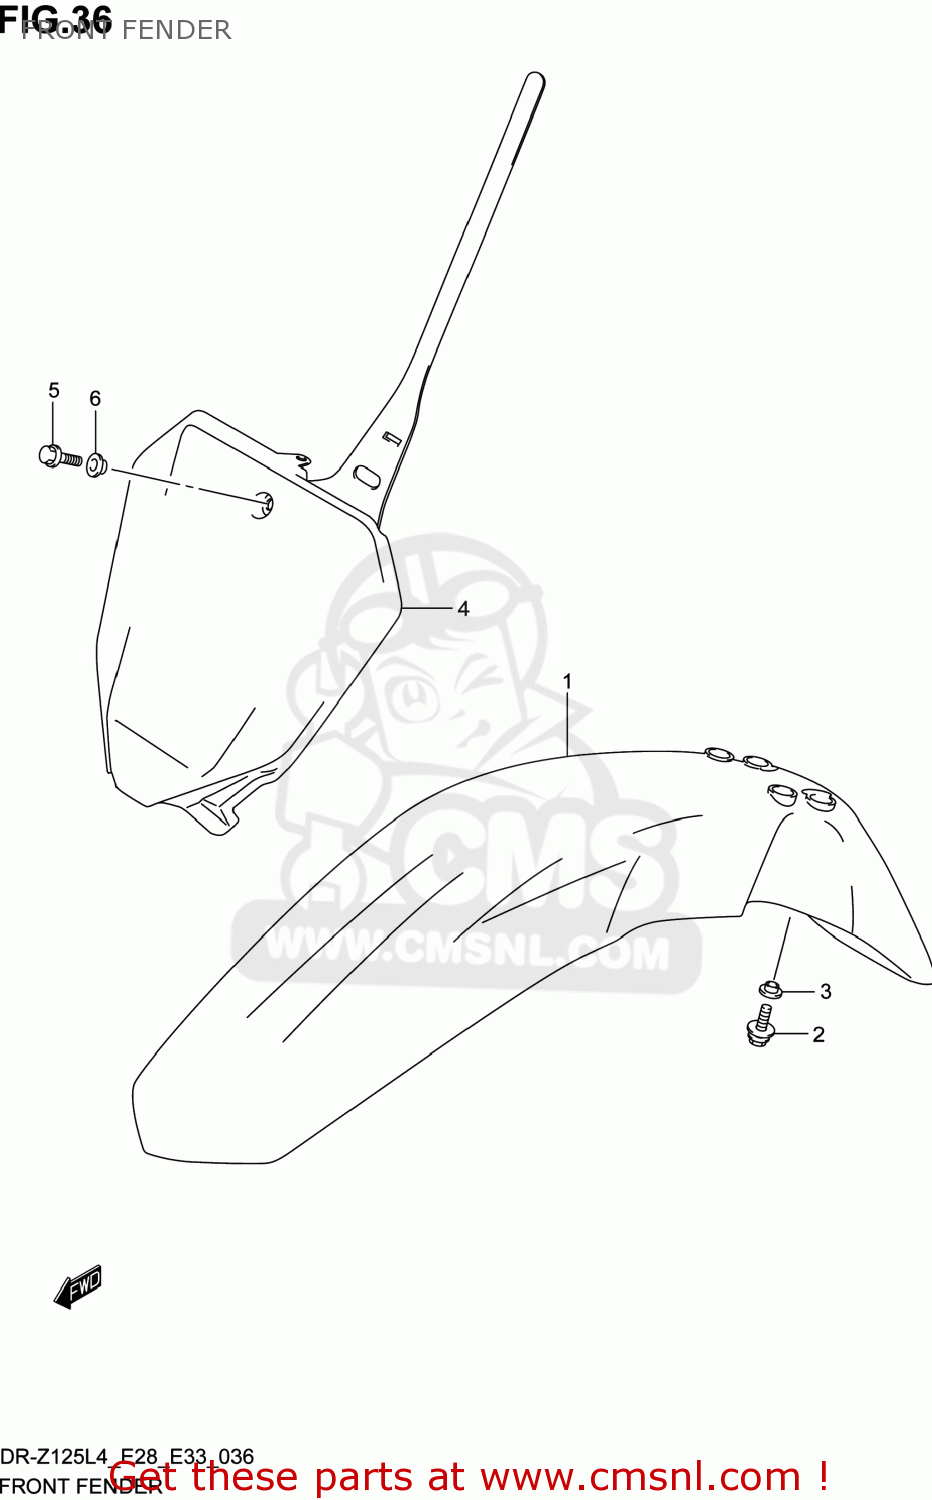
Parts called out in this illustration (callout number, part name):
1	FENDER,FR
2	BOLT(6X16)
3	WASHER
4	PLATE,NUMBER FR
5	BOLT
6	WASHER
